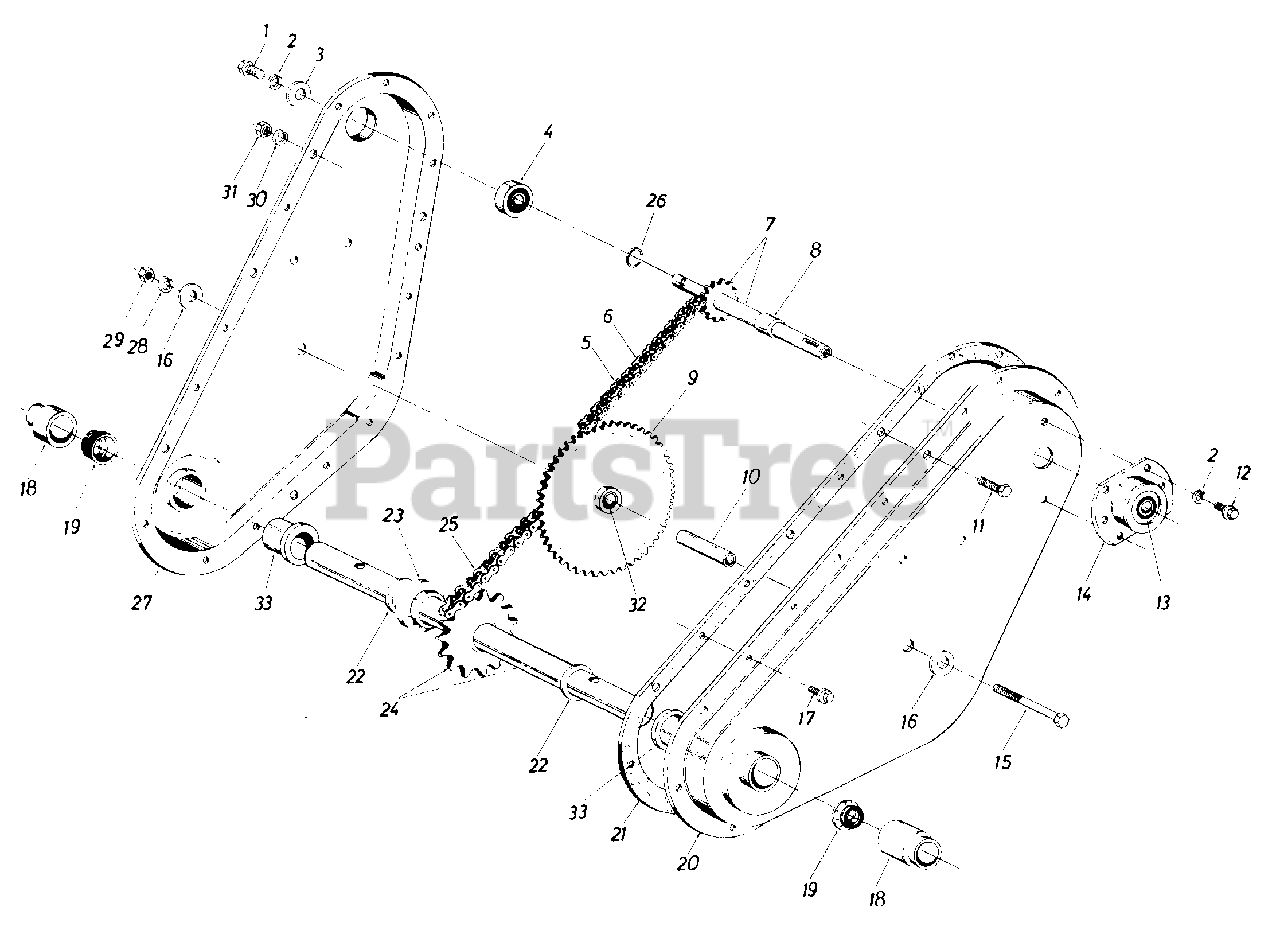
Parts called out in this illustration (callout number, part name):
1	Hex L-Scr. 1/4-28 x .625" Lg.
2	L-Wash. 1/4" Scr.
3	Fl-Wash. .25" I.D. x .93" O.D. x .125" Thk.
4	Bearing .62" I.D. x 1.38" O.D. x .437" Thk.
5	#35 Chain 3/8" Pitch x 52 Links Endless
6	Master Link
7	Input Shaft Assembly
8	Spacer
9	Sprocket Assembly
10	Sprocket Hub Tubing 3/8" I.D. x 5/8" O.D. x 1.9" Lg.
11	Hex Scr. 5/16-18 x .625" Lg.
12	Hex Wash. Hd. Self-Tap Scr. 1/4-20 x .50" Lg.
13	Bearing .625" I.D. x 1.38" O.D. x .437" Thk.
14	Bearing Housing
15	Hex Scr. 3/8-24 x 2.75" Lg.
16	Fl-Wash. 3/8" I.D. x 1.25 O.D. x .100 Thk.
17	Hex Wash. Hd. Self-Tap Scr. 1/4-20 x .50" Lg.
18	Dust Cap
22	Thrust Wash. 1.00" I.D. x .030" Thk.
23	Step Spacer
24	Tine Shaft Assembly
25	#50 Chain 5/8" Pitch x 46 Links Endless
26	Snap Ring 5/8" Dia. Shaft
29	Hex Nut 3/8-24 Thd.
30	L-Wash. 5/16" Scr.
31	Hex Nut 5/16-18 Thd.
32	Bearing
33	Bearing
